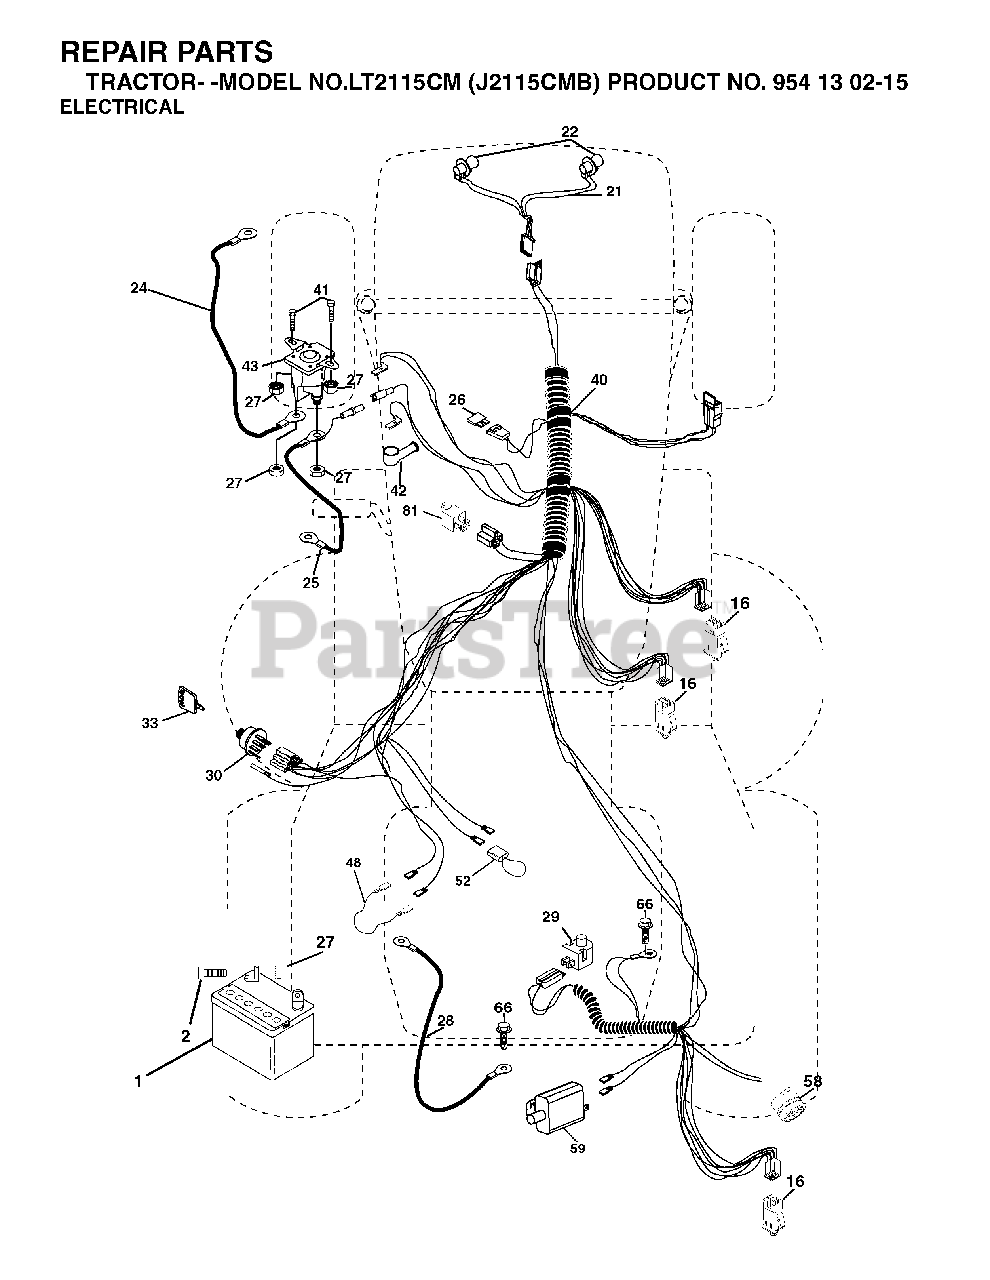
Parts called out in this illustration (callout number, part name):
1	BATTERY 12V .35 AMP
16	SWITCH INTERLOOK PUSH-IN
21	HARNESS.W/LIGHT SOCKET
22	LIGHTBULB
24	BATTERY CABLE GT
25	CABLE BATTERY
26	FUSE 20AMP
27	NUT
28	CABLE GROUND
29	SWITCH SEAT
30	IGNITION SWITCH
33	KEY MLD GEN DELTA
42	TERMINAL COVER
43	SOLENOID
52	WIRE PROTECTION LOOP
58	BUZZER
81	RELAY.ASSY.T
